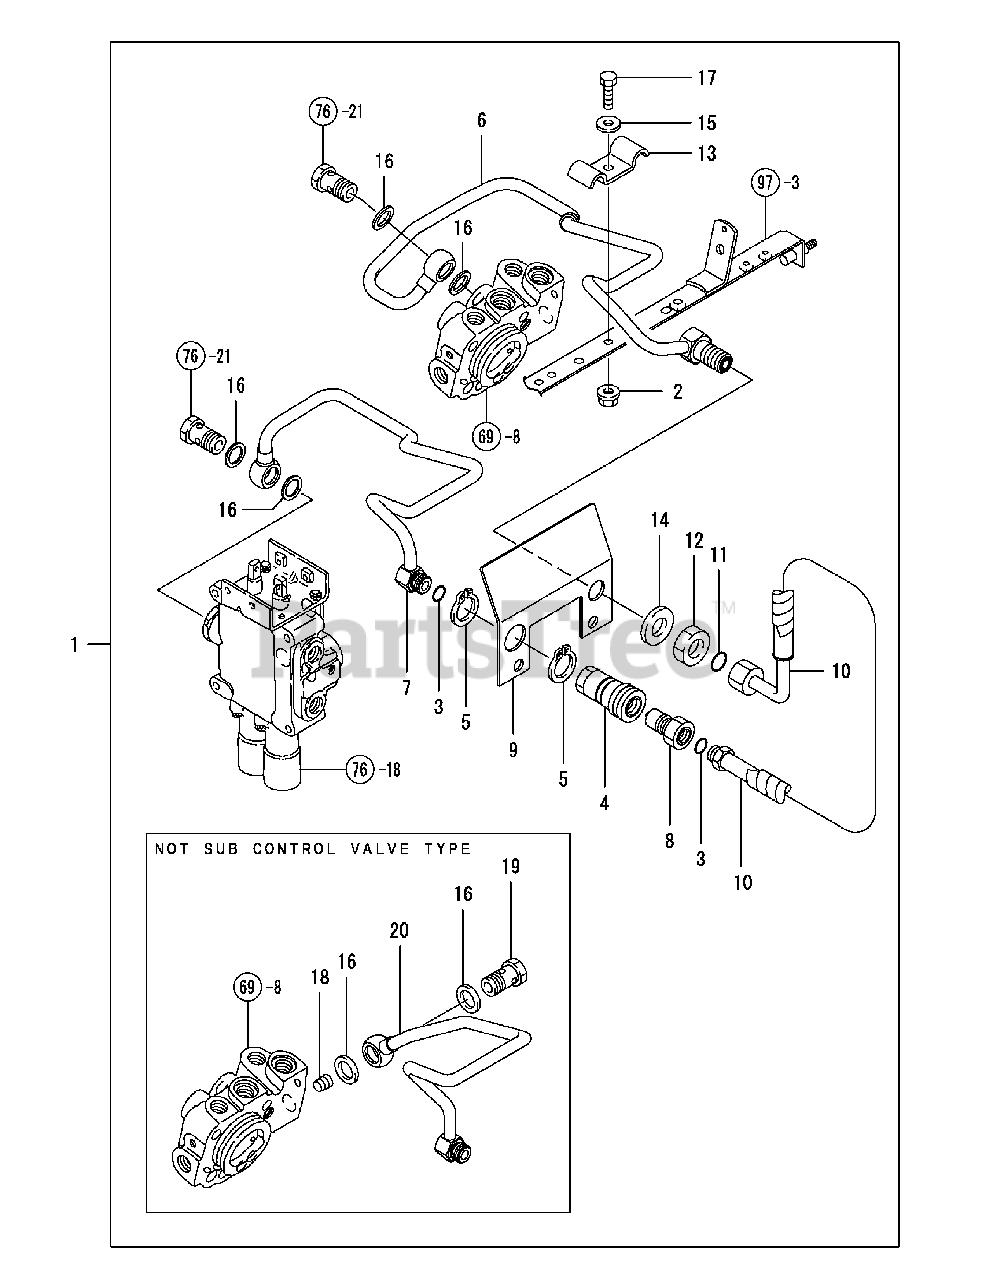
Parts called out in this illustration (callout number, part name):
1	REAR AUX.HYD. KIT
2	NUT W/WASHER 8
4	COUPLER,QUICK 3/8F
8	COUPLER,QUICK 3/8M
10	HOSE,REAR HYDRAULIC
11	PACKING,CH178X 0124H
14	WASHER 20,POLISHED
17	BOLT M 8X 20 PLATED
20	LINE,PRESSURE
